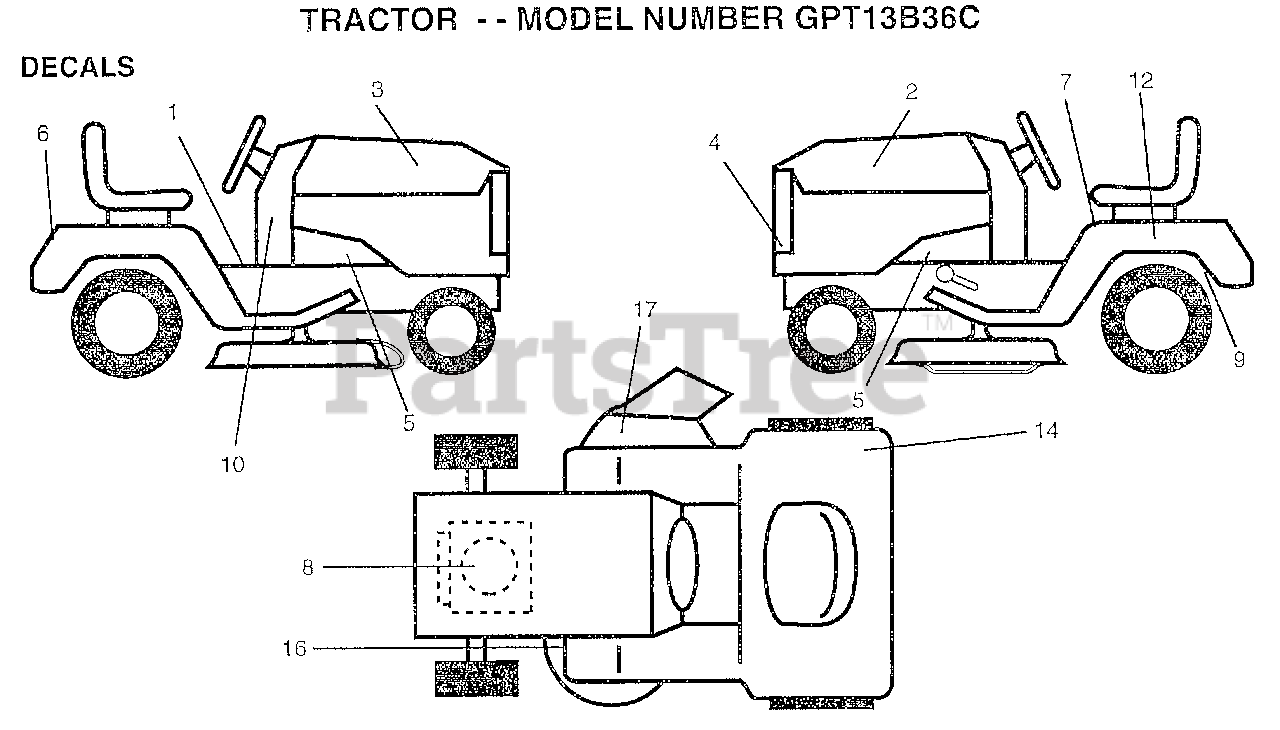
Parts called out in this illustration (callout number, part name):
1	DECAL CLUTCH/BRAK
2	DECAL.HD.LH.TAGA
3	DECAL.HD.RH.TAGA
4	DECAL.GRILLE.TAGA
5	"DECAL CHASSIS,HOT"
6	DECAL, FENDER
7	DECAL.READ.O.MANU
8	DECAL HP ENGINE
9	DECAL.DRAWBAR.LDL
10	DECAL.EURO.ST.CE.
12	DECAL.BATRY.3-3908
16	DECAL.DANGER.CUTF
17	DECAL.V.BELT
